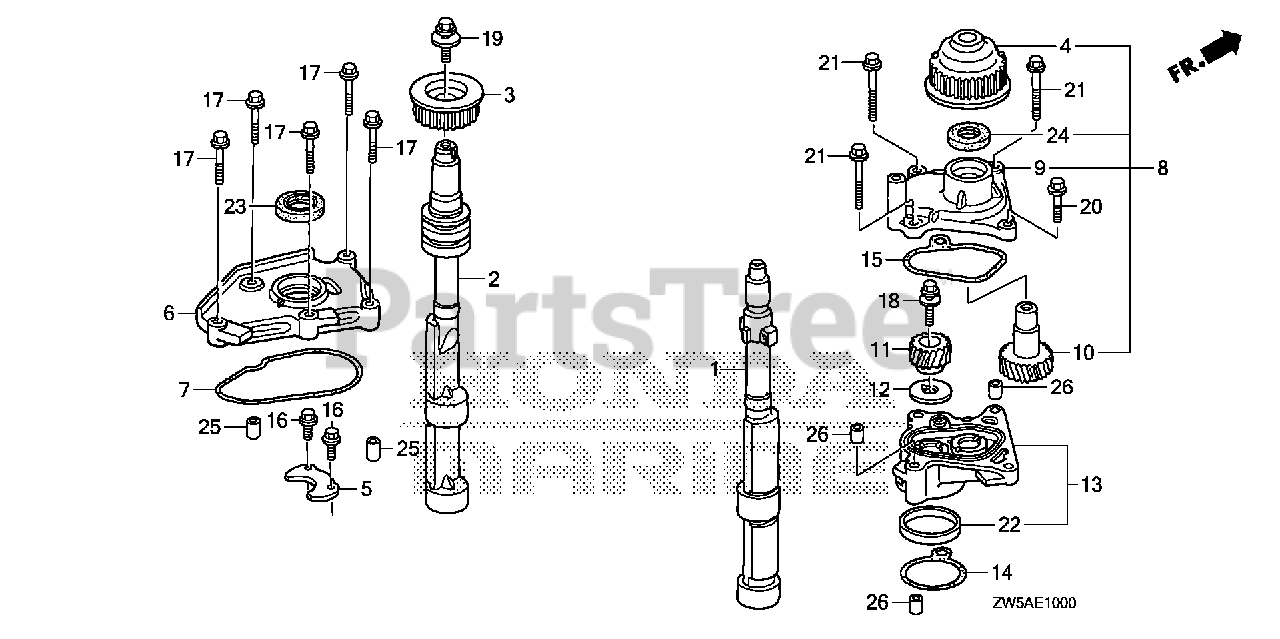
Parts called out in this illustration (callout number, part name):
1	SHAFT, RR. BALANCER
2	SHAFT, FR. BALANCER
3	PULLEY, BALANCER BELT DRIVEN (FR)
4	PULLEY, BALANCER BELT DRIVEN (RR)
5	METAL F, THRUST BALANCER SHAFT
6	COVER, BALANCER SHAFT
7	O-RING, BALANCER COVER
8	CASE, BALANCER GEAR
9	CASE, BALANCER GEAR
10	GEAR, BALANCER DRIVE
11	GEAR, BALANCER DRIVEN
12	WASHER, THRUST
13	SPACER, GEAR CASE
14	O-RING, GEAR CASE SPACER
15	GASKET B, OIL PUMP (ARAI)
16	BOLT, FLANGE (6X18)
17	BOLT, FLANGE (6X35)
18	BOLT-WASHER (8X33)
19	BOLT-WASHER (8X22)
20	BOLT, FLANGE (8X25)
21	BOLT, FLANGE (8X65)
22	PIN, DOWEL (49X10)
23	OIL SEAL (27X41X8) (NOK)
24	OIL SEAL (18X33X6)
25	PIN, DOWEL (8X14)
26	PIN, DOWEL (10X12)
